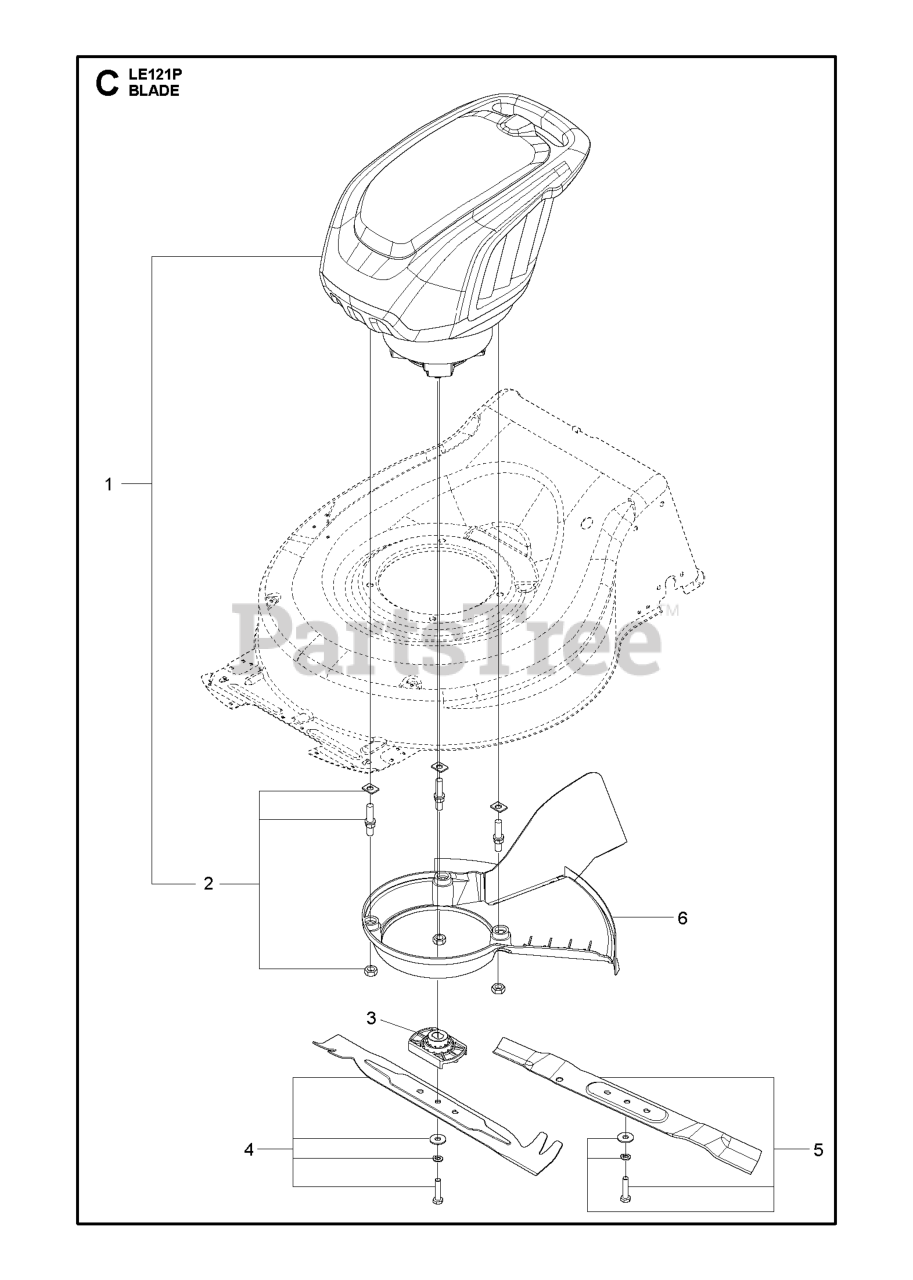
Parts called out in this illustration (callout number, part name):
1	POWER UNIT LE221R
2	SCREW KIT WASHER, SCREW AND BO
3	BLADE SUPPORT TRANSMISSION SYS
4	BLADE KIT 20" INCL BOLT AND WA
5	BLADE KIT 20" INCL BOLT AND WA
6	BELT COVER 20 INCH MOWER
